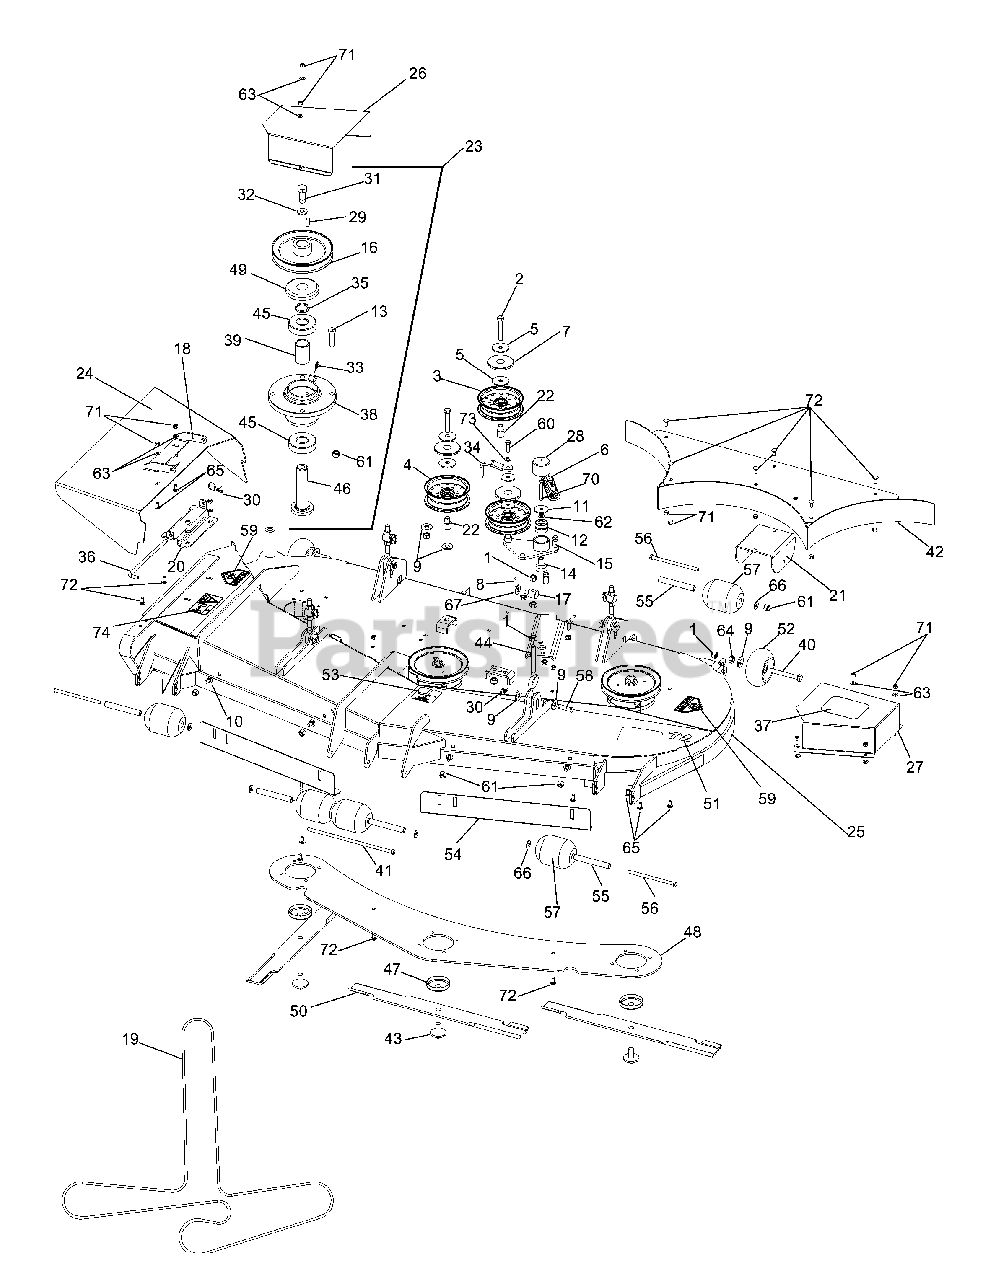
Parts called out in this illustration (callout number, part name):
1	NUT 1/2-13 HEX NYLOC ZD
2	SCREW, 1/2C X 3 HEX CAP
3	IDLER PULLEY
4	IDLER PULLEY (TALL)
5	ISOLATOR WASHER
6	DECK SPRING
7	TOP DUST CAP
8	PIN COTTER 1/8 X 1 ZD
9	WASH USS FLAT 1/2
10	RHSNB 3/8-16 X 3/4 GR5 ZD
11	WASHER, 3/8 SPEC
12	BEARING, BALL
13	HCS 3/8C X 1 1/2
14	BEARING PIVOT SPACER
15	ARM, IDLER - WELDMENT
16	PULLEY, 7.50 O.D.
18	HINGE, DISCHARGE CHUTE, BLUE
19	BELT-DECK, 72
20	SUPT - CHUTE HINGE PAINTED
21	REAR CENTER ROLLER BKT 72 BLK
22	SPACER - IDLER
23	SPINDLE ASSEMBLY, 72
24	CHUTE - 72 PAINTED
25	DECK W/DECAL 72 GRIZZLY
26	PULLEY GUARD 72, RH PAINTED
27	PULLEY GUARD 72, LH PAINTED
28	CAP, VINYL
29	KEY - 1/4 X .88
30	PIN, COTTER 1 3/4
31	1/2-20 UNF X 1 1/4 HHBLT
32	WASHER .525 X 1.375 X .25
33	ZERK, 3/16, DRIVE IN
34	GUIDE, BELT
35	SPACER .25
36	DEFLECTOR PIN
37	REAR FLOOR PAD-LH
38	DECK HUB MACHINED
40	HCS 1/2-13 X 4 GR 5 ZD
41	3/8-16X12 HHB G5
42	W-BAFFLE WLDT
43	BLADE BOLT/WASHER
44	BOLT, EYE
45	BEARING - 6305 - 2RS
46	SHAFT SHORT
47	TRASH GUARD
48	HUB STIFFENER PLATE
49	TRASH GUARD
50	BLD 72" HI LIFT FUS
51	DECAL, DECK 72"
52	GUAGE WHEEL
53	DECAL, BELT ROUTING (18656)
54	BLOW BY BAFFLE
55	BUSHING
56	3/8-16 X 6-1/2 HHB GR8
57	ROLLER 3-3/4 DIA. X 4-1
58	CLEVIS PIN 1/2X1-3/4LG
59	DECAL, CPSC
60	HCS 3/8C X 1 1/4 GR5
61	NUT 3/8-16 NYLOC
62	WASHER 3/8 SAE FLAT
63	FLAT WASHER 5/16 SAE
64	NUT HEX 1/2
65	BOLT 5/16C X 3/4" CARRIAGE
66	WASHER 3/8 FLAT
67	WASHER 1/2 FLAT
68	HCS 3/8C X 1
69	NUT 3/8C WHIZ
70	HCS 3/8C X 2 1/2
71	NUT 5/16 NYLOC
72	RHSSNB 5/16C X 1.0
73	SLW 3/8 STD
74	DECAL, EURO SEVERING
